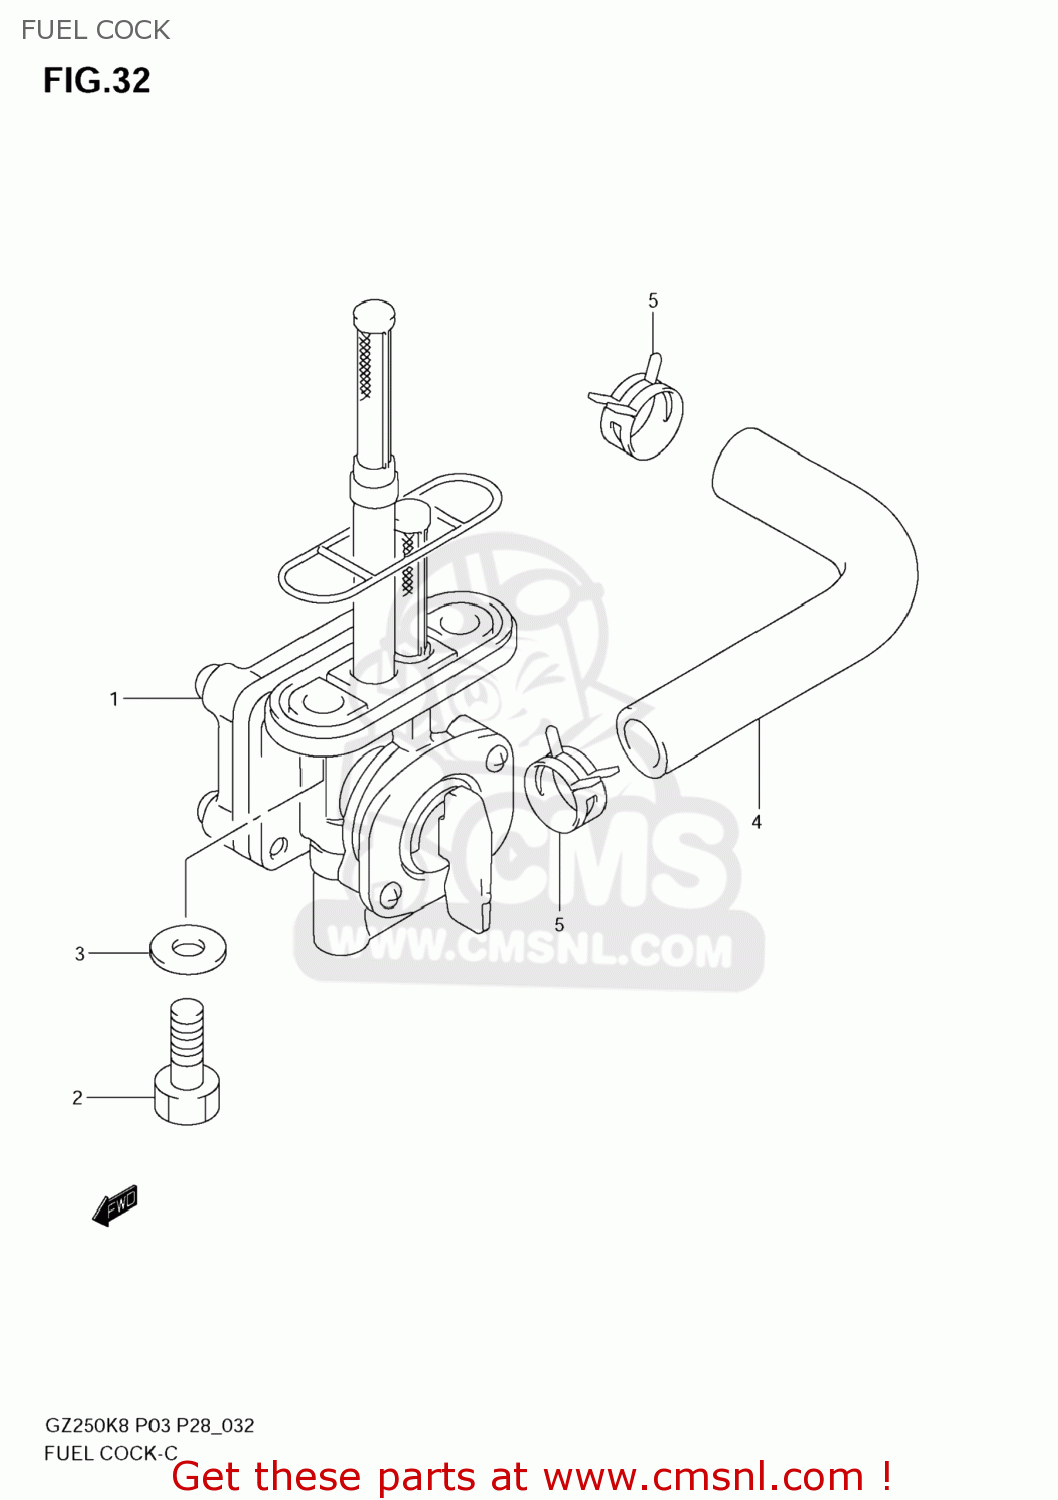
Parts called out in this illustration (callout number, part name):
1	COCK ASSY,FUEL
2	BOLT(6X20)
3	GASKET(6.4X11.5X0.8) (NAS)
4	HOSE(7X12X600)
5	CLIP
